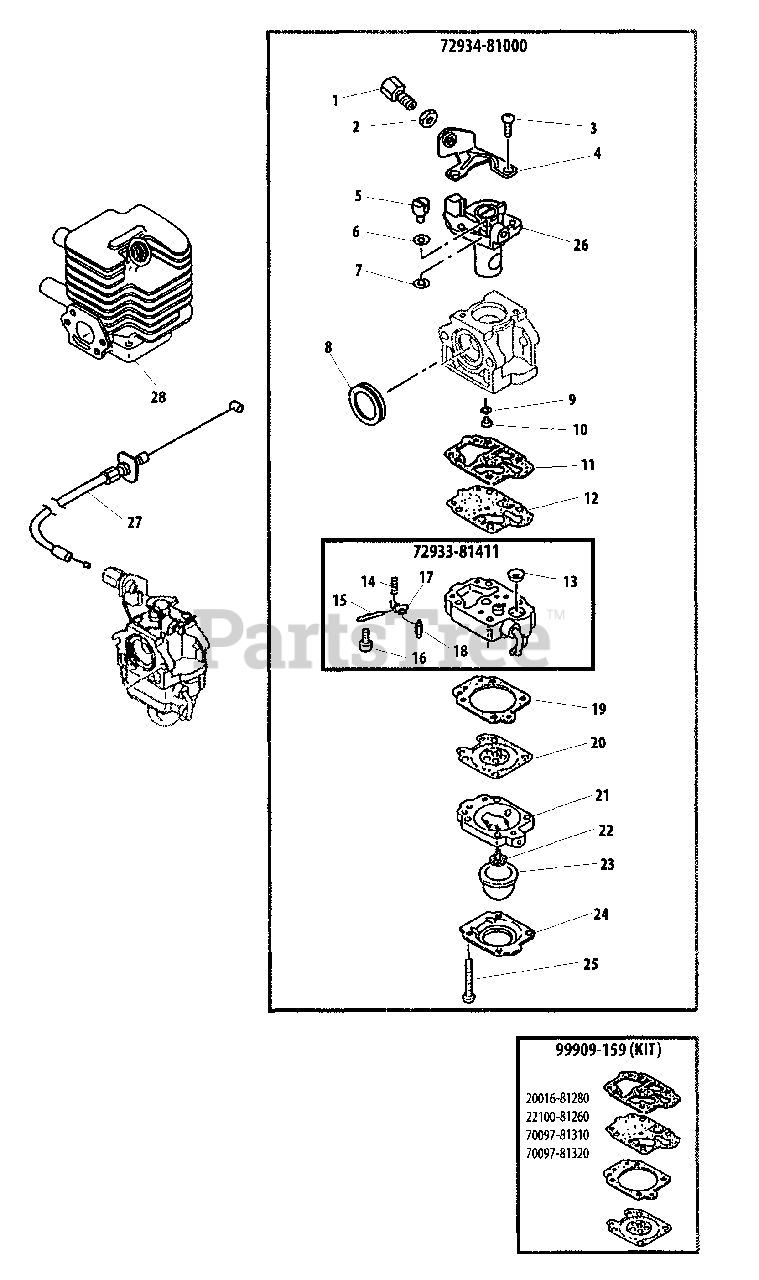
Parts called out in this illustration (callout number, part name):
1	ADJUSTER, THROTTLE CABLE
2	NUT, ADJUSTER LOCK M7
3	SCREW
4	BRACKET, THROTTLE CABLE
5	SWIVEL
6	WASHER
7	E-RING
8	RING, PACKING
9	O-RING
9	BODY ASSY, PUMP
10	JET
11	GASKET, PUMP
12	DIAPHRAGM, PUMP
13	SCREEN, FUEL INLET
14	SPRING, METERING LEVER
15	PIN, METERING LEVER
16	PIN, METERING LEVER
17	LEVER, METERING
18	VALVE, INLET NEEDLE
19	GASKET, METERING DIAPHRAGM
20	DIAPHRAGM, METERING
21	BODY ASSY, PURGE
22	VALVE, CHECK
23	BULB, PURGE
24	RETAINER, PURGE BULB
25	SCREW
26	THROTTLE VALVE ASSY
27	CABLE, THROTTLE
28	CYLINDER
